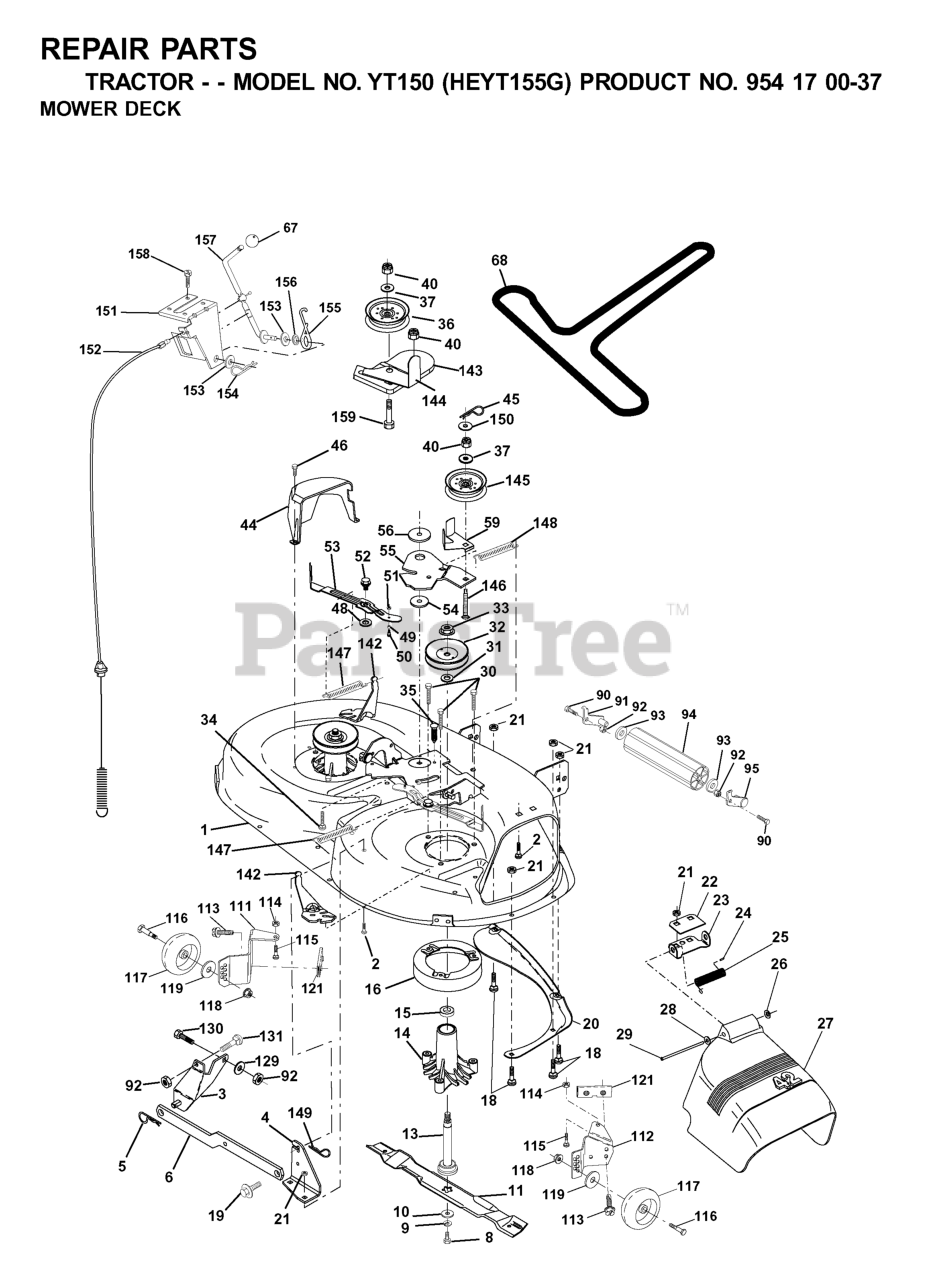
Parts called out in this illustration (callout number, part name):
1	42" DECK KIT
2	RP BOLT 5/16-18 X3/4 ZN/YEL GR
3	BRKT ASM SWAY BAR
4	BRACKET SWAY BAR 42" DECK
5	RETAINER-SPRNG RB
6	REAR SUSP ARM
8	BLADE BOLT
9	LOCKWASHER
10	WASHER.BLADE
11	Blade Mower 42" High Perf.
13	SHAFT ASM VENT
14	HOUSING.MANDREL.VENTED (MACHD)
16	STRIPPER
18	BOLT
19	BOLT SHD 5/16-18
20	BAFFLE.VORTEX
21	LOCKNUT
22	STIFFENER BRACKET
23	DEFLECTOR BRACKET
24	CAP-SLEEVE LT
25	SPRING TORSION
26	NUT PUSH M
27	SHIELD DEFLECTOR
28	Washer 11/32 x 5/8 x 16 Ga SD
29	ROD.HINGE
30	SCREW THDROL ROLLING WASHER HD
31	WASHER
32	PULLEY/MANDREL
33	NUT
35	FASTENER.XMAS.TREE
36	FLAT IDLER PULLEY
37	WASHER
44	GUARD MANDREL LH BLACK
45	RETAINER M
46	SCREW.1/4-20X5/8
49	ROLLER ASM CAM FOLLOWER
52	BOLT.SHOULDER.5/16-18
53	ARM
54	HARDENED WASHER
55	ARM IDLER 42" MOWER LT/YT
56	SPACER.RETAINER.MOWER
59	GUARD, BELT
67	KNOB T (3/8 HOLE)
68	BELT V SECONDARY
90	BOLT
91	BRACKET LH (A)
92	NUT
93	Washer 1 17/32 X 7/8 X 16 Ga
94	NOSE ROLLER
95	BRACKET RH (B)
111	BRACKET WHEEL GAUGE LH 42" DK
112	BRACKET WHEEL GAUGE RH 42" DK
113	Screw Tapping 5/16-18 Unc
114	NUT
115	BOLT.CARR.5/16-18X1/2
116	BOLT M
117	WHEEL.GAUGE.STANDARD
118	LOCKNUT
119	WASHER.5/16.FLAT.STE.STD.
121	BRACKET.EXTRUDED.GAGE.WHEEL
129	WASHER
131	BOLT D
142	ARM SPRING BRAKE MOWER
143	BRACKET, ARM IDLER
144	DNO KEEPER.BELT.42".CLUTCH.CBL
145	PULLEY
146	BOLT, CARRIAGE IDLER BLACK
147	SPRING EXTENSION
148	IDLER RETURN SPRING
149	SPRING.RETAINER.YELLOW.ZINC
151	BRACKET.CLUTCH.CABLE
152	CLUTCH CABLE 42"
153	WASHER FLAT 3/8"
154	SPRING RETAINER
155	SPRING RETENTION LEVER
156	SPACER.CLUTCH.CABLE
157	ROD CLUTCH CABLE 3/8"
158	SCREW LT
